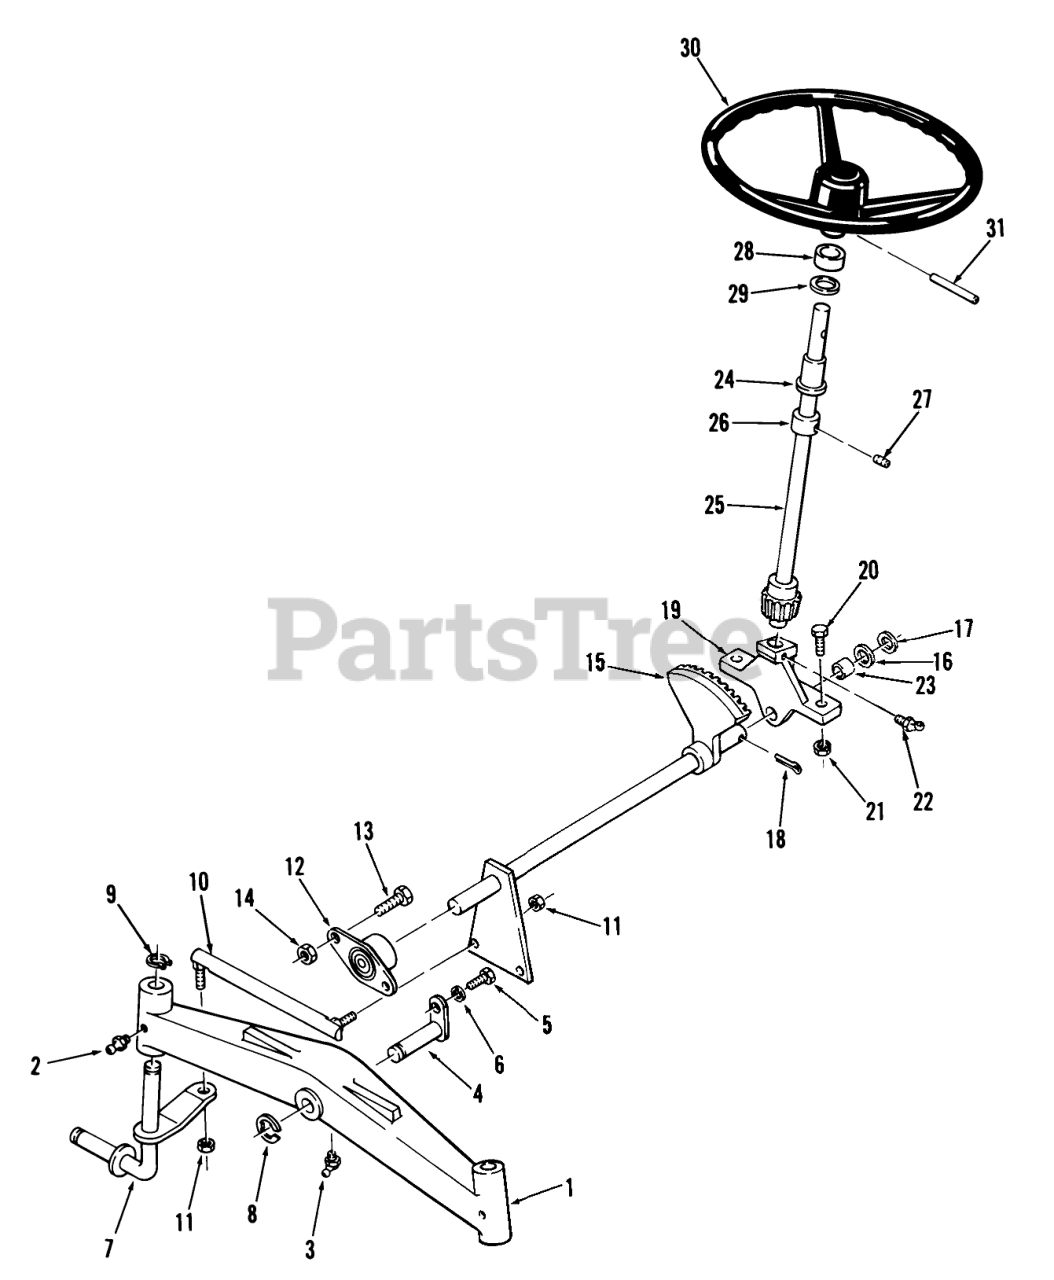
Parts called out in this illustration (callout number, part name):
1	AXLE-FRONT
2	Zerk
3	FITTING-GREASE
4	PIN AND PLATE ASM
5	H H C S
6	Lockwasher
7	Front Spindle RH
7	Front Spindle LH
8	E-RING
9	Snap Ring
10	Tie Rod RH
10	Tie Rod LH
11	NUT-6
12	BEARING-FLANGED
13	Bolt
14	Nut
15	Assy-Steering
16	WASHER-SHIM
17	WASHER
18	PIN-4
19	Support
20	Bolt
21	Nut
22	FITTING-GREASE
23	BEARING-BRONZE
24	BEARING
25	Upper Steering Shaft
26	Collar
27	SCREW-SET
28	COLLAR
29	WASHER-BOWED
30	STEERING WH 13" PLAS
31	Pin-Roll
